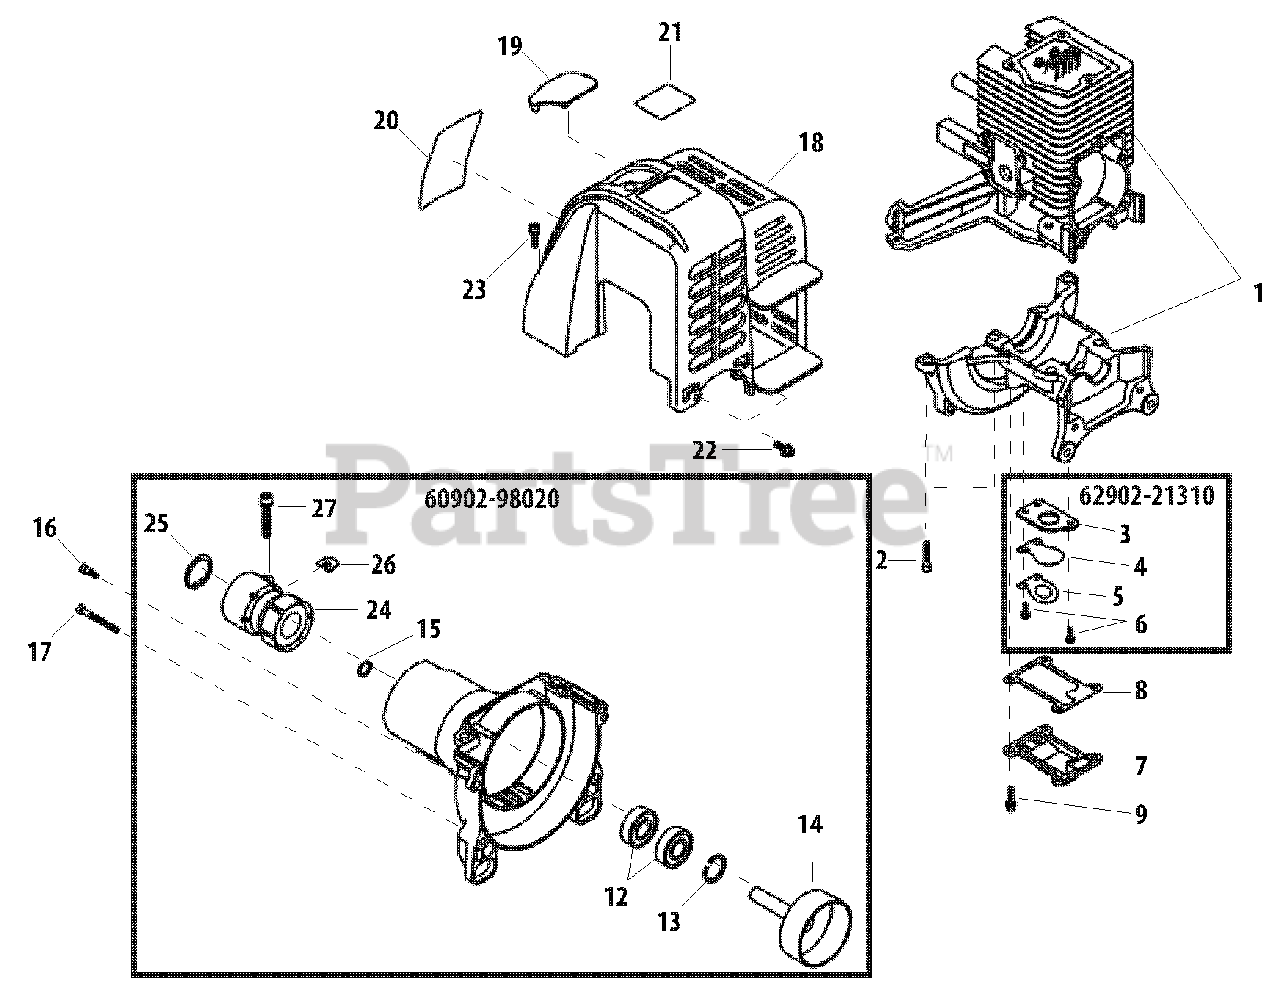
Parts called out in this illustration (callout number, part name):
1	CYLINDER BLOCK SET
2	SCREW - 5X16
3	PLATE, REED BACKING
4	VALVE, REED
5	STOP, REED VALVE
6	SCREW - 3X10
7	COVER, REED VALVE
8	GASKET, REED VALVE
9	SCREW - 4X12
12	BEARING, BALL - 6000
13	RING, RETAINING - 26
14	DRUM, CLUTCH
15	RING, RETAINING
16	SCREW - 5X16
17	SCREW - 5X35
18	COVER, ENGINE
19	GROMMET
20	LABEL - C4
21	LABEL - TRADE
22	SCREW - 4X16
23	SCREW - 4X16
24	CLAMP, MAIN PIPE
25	RING, RETAINING - 40
26	SHIM
27	SCREW - 5X22
60902-98020	FAN CASE ASSY
62902-21310	REED VALVE ASSY
